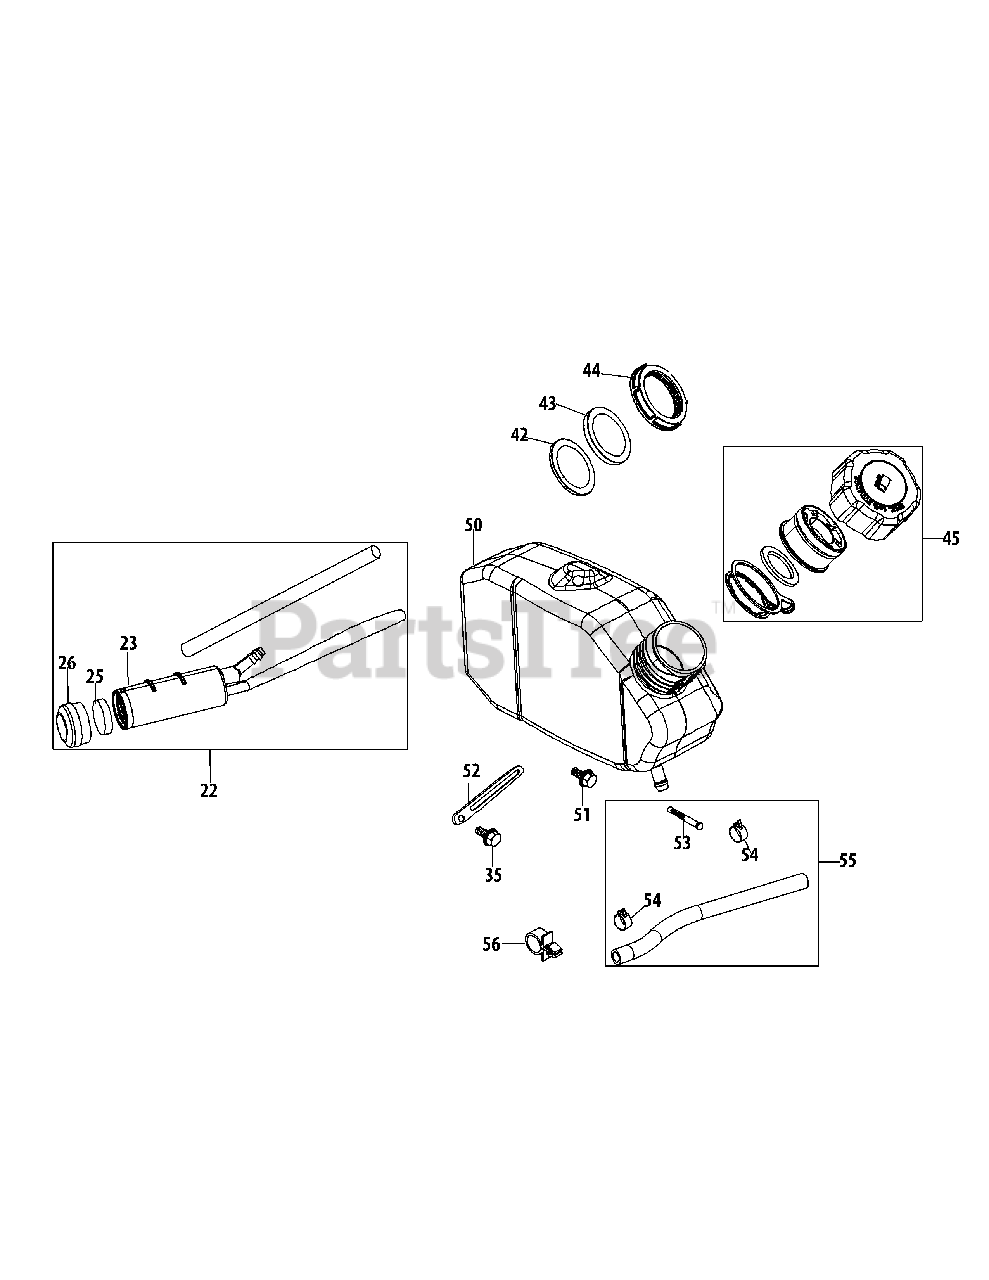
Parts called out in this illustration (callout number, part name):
22	Carbon Canister Assembly
23	Carbon Canister
25	Carbon Canister Filter
26	Carbon Canister Filter Cap
35	Bolt M6X14 Multi-Purpose
42	Fuel Tank Lower Grommet
43	Fuel Tank Upper Grommet
44	Fuel Tank Nut
45	Fuel Cap Assembly
51	Bolt M6X12 Multi-Purpose
52	Flexible Clamp, Vent Hose
53	Fuel Line Kit
54	Fuel Hose Clamp
56	Plastic Support Clamp
